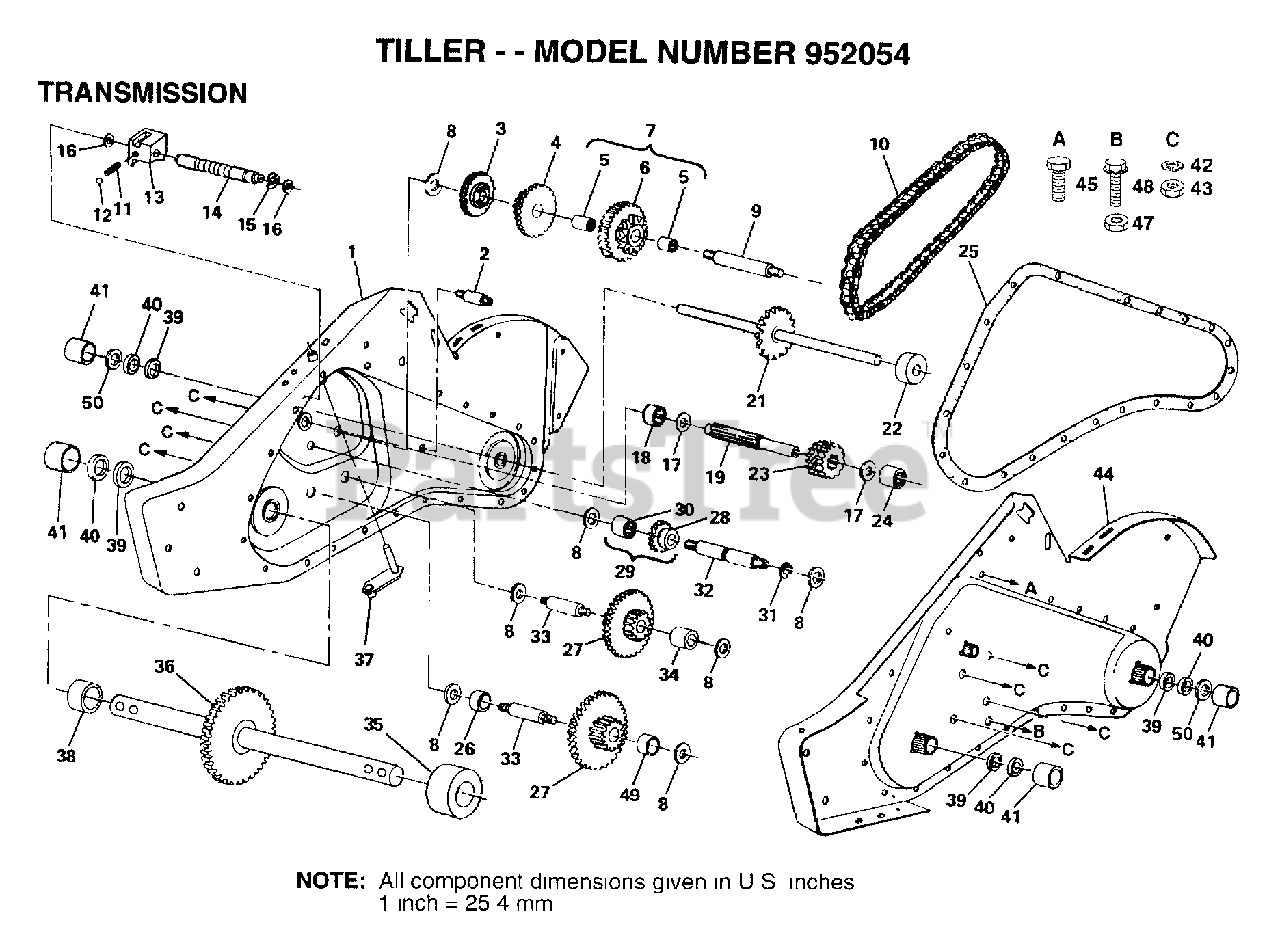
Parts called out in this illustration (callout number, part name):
2	BOLT TI
3	REVERSE GEAR TI
4	CLUSTER GEAR TI
5	"CRT, BEARING"
7	SPROCKET ASSY TI
8	WASHER
9	REDUCTION SHFT TI
10	CHAIN TI
11	SPRING-SHIFT CRT
13	SHIFT FORK TI
14	SHIFT SHAFT TI
15	KLIP RING
16	WASHER SEAL CRT
17	"T, BEARING"
18	"TI, BEARING"
19	SHAFT INPUT
21	SHAFT TINE CRT
22	SPACER CRT
23	INPUT PINION TI
24	NEEDLE BRNG LT
25	GEARCASE GSKT TI
26	SPACER CRT
27	GEAR CLUSTER CRT
28	REVERSE GEAR TI
29	GEAR ASSY TI
30	NEEDLE BEARING TI
31	KLIP RING
32	REVERSE SHAFT TI
33	SHAFT CRT
34	SPACER CRT
35	SPACER CRT
36	SHAFT ASSY CRT
37	BRACKET ASM SHIFT
38	SPACER CRT
39	OIL SEAL STD
40	SEAL RING RUBBER
41	CUP.FORMED.
42	LOCKWASHER
43	NUT.ASF.HEX.7/16
45	SCREW 5/16-18X5/8
47	NUT.HEX.5/16-18
48	BOLT TI
49	SPACER CRT
50	RING SPIRAL CRT
